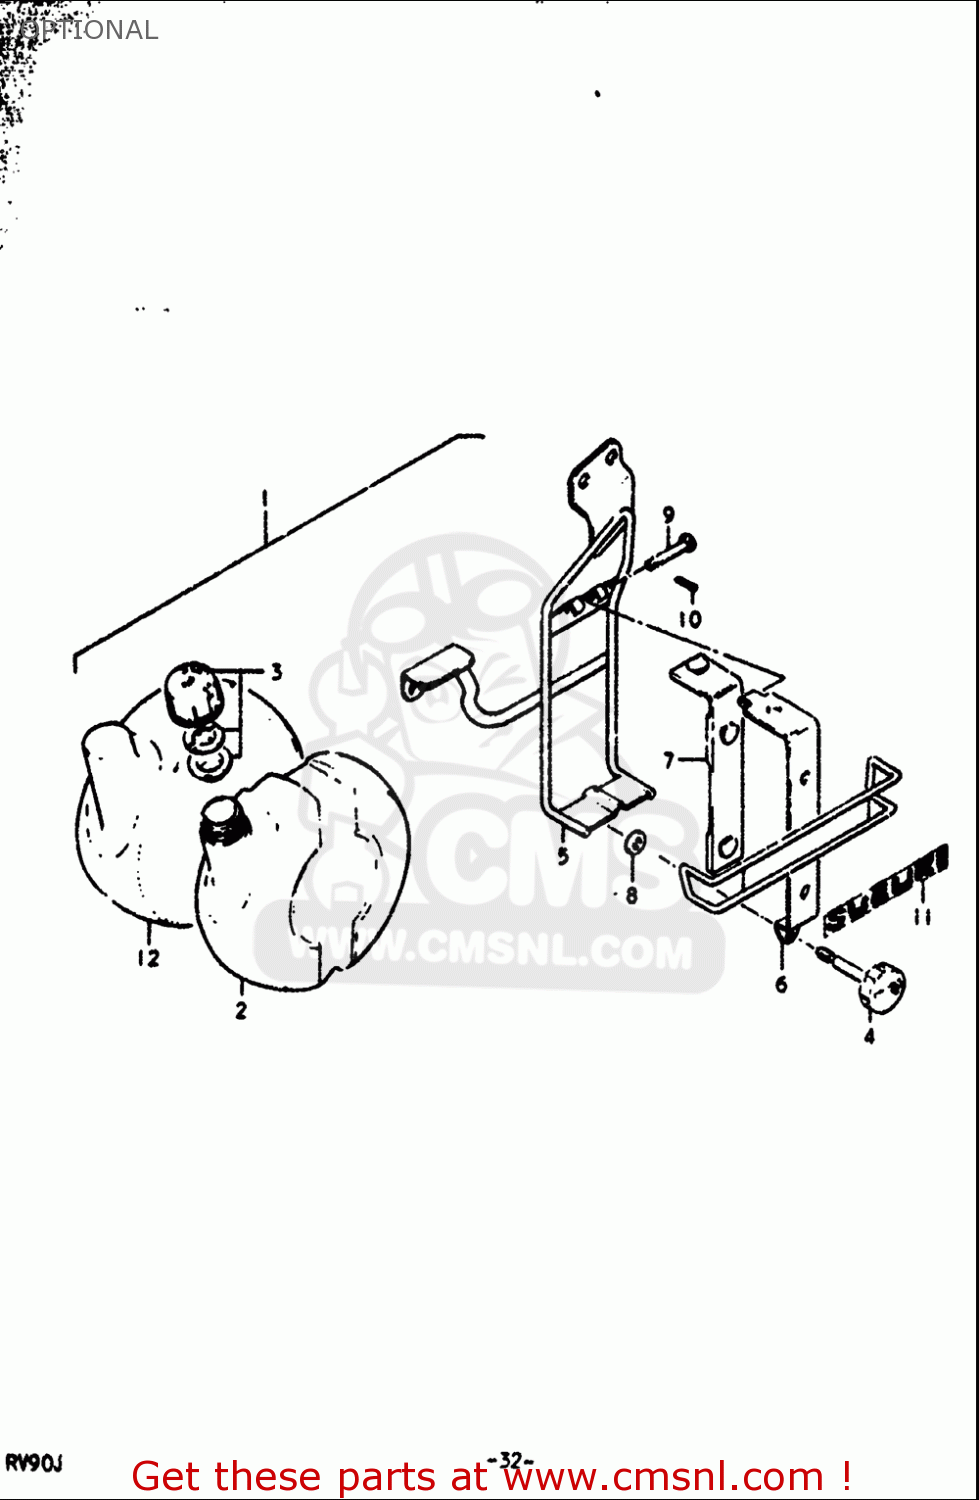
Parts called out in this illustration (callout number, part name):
3	CAP SET,FUEL TANK FILLER
8	NUT
9	PIN
10	PIN
11	EMBLEM,SUB FUEL TANK
